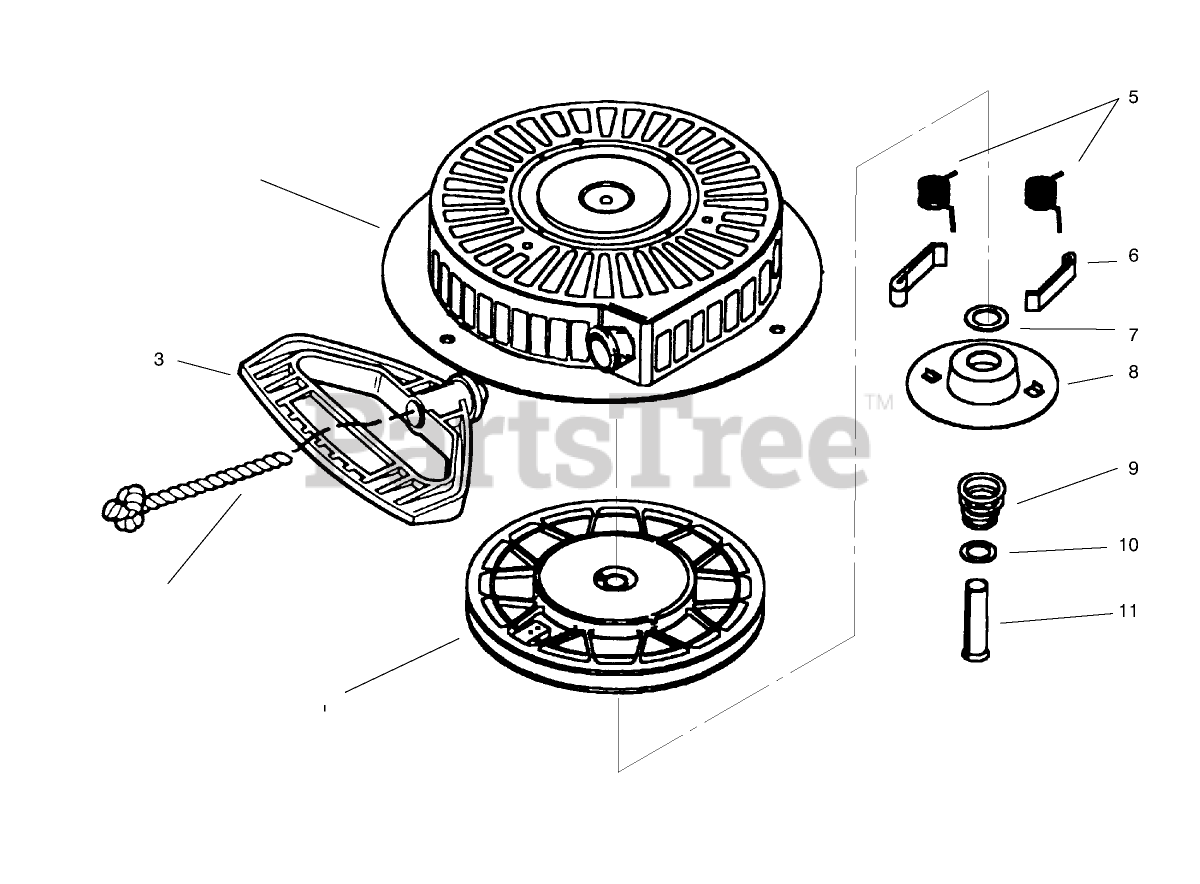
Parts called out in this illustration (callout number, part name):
1	Pulley and Rewind Spring ASM
2	Rope-Starter (98 cut to length)
3	Handle-Starter, Mitten Grip
4	Starter Housing ASM
5	Spring-Dog
6	Dog-Starter
7	Washer
8	Retainer
9	Spring-Brake
10	Washer
11	Pin, Spring (Incl. Ref. #7)
